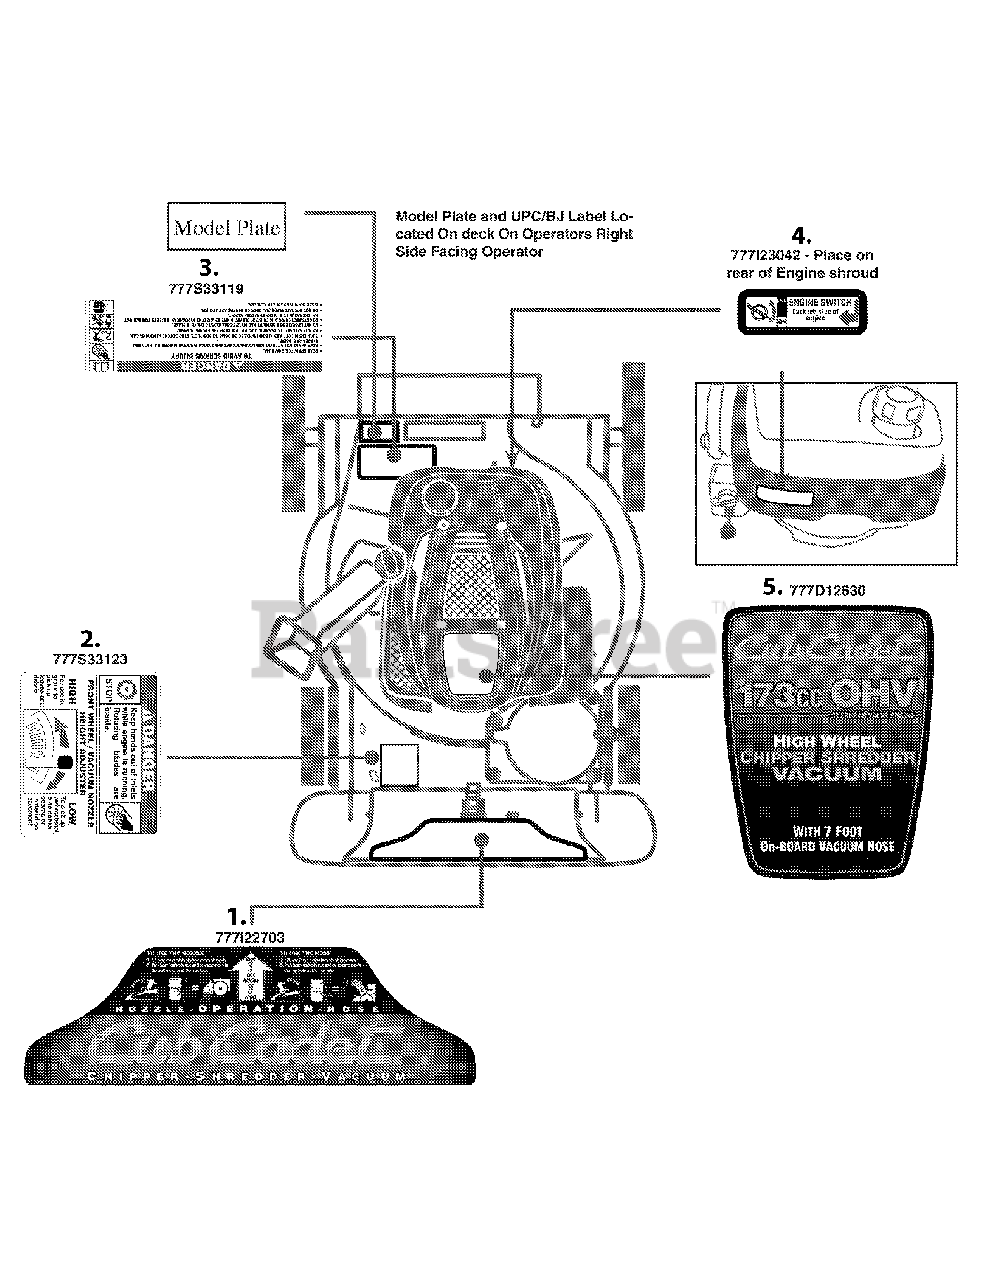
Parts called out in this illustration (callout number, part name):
1	LABEL-CSV NOZZLE
2	LABEL-CSV BLADES DANGER
3	LABEL-CSV DANGER
4	LABEL-OFF ON SWITCH
5	LABEL-173CC SHROUD
